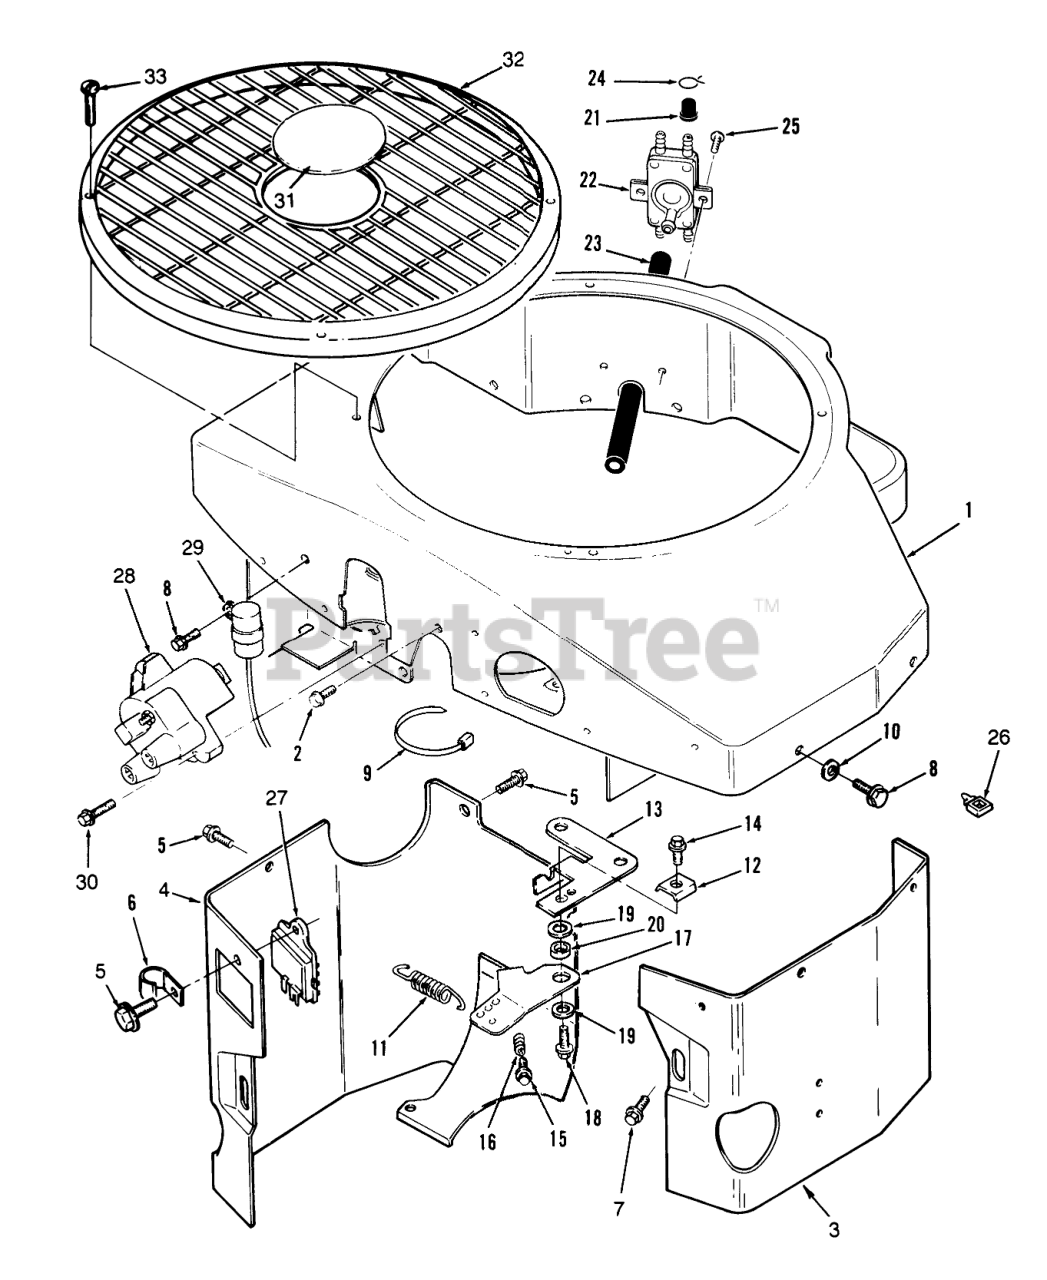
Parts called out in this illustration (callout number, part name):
1	HOUSING
2	HEX HD CAPSCREW
3	CYLINDER AIR HSG L H
4	HOUSING CYL RH
5	SCREW-HWH
6	Clip
7	Bolt
8	SCREW-HH
9	Bolt
10	WASHER-FLAT
11	Spring
13	Bracket
14	Bolt
15	SCREW-TAP
16	SPRING
18	SCREW-HWH
19	WASHER-FLAT
20	BUSHING
21	CAP-FUEL OUTLET
22	FUEL-PUMP
23	Hose
24	CLAMP
25	SCREW-TAPPING PAN HD
26	Clip
27	Regulator
28	Coil-Ignition
29	Condenser
30	Bolt
31	Plug
32	Guard
33	Screw
